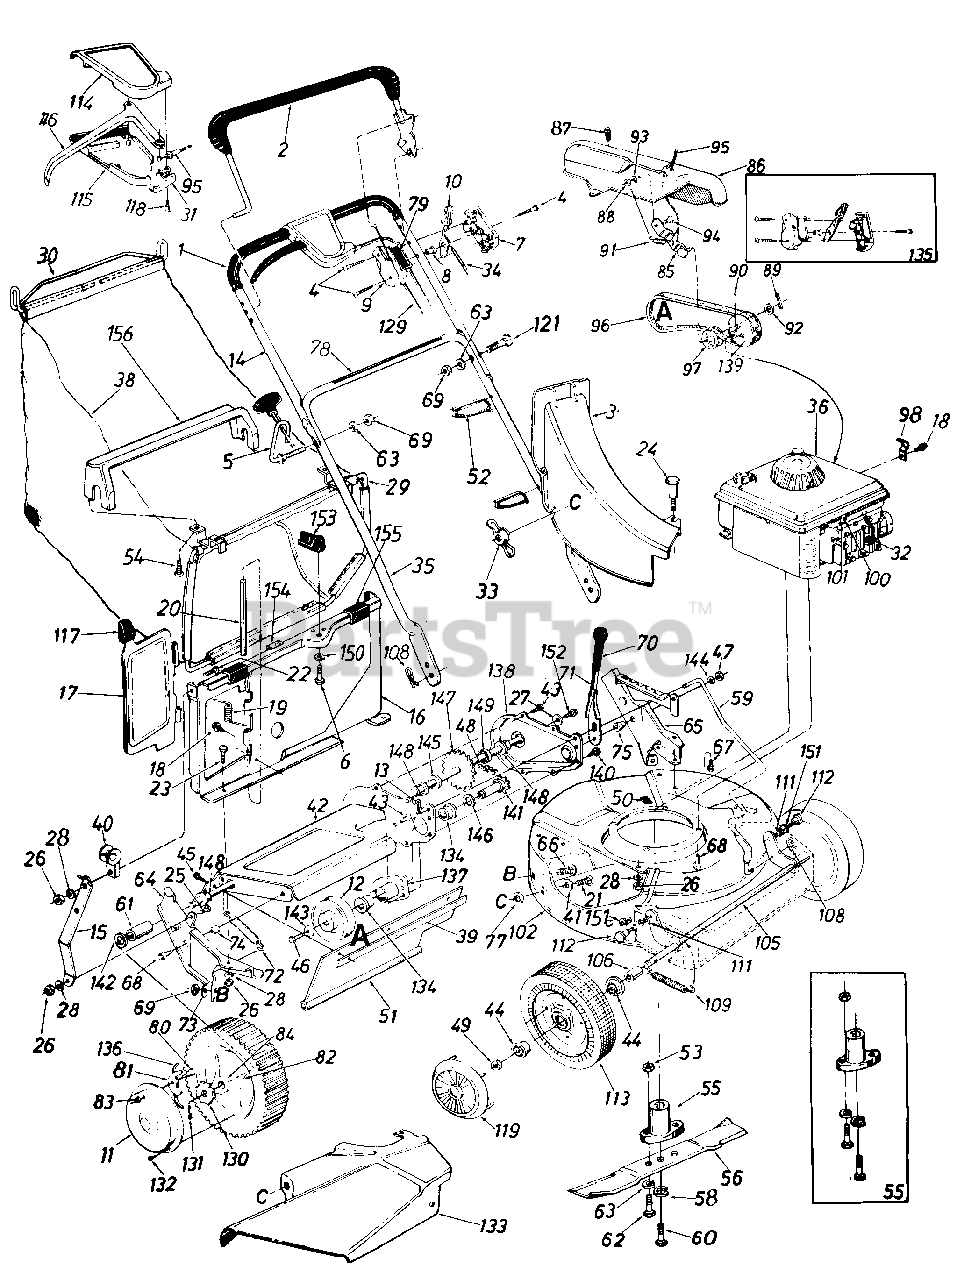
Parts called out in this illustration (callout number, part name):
2	Control Handle Assembly
3	Top Discharge Chute Assembly
4	Truss Machine Screw #12 x 1.5 "
5	Rope Guide Bolt
6	Hex Tap Screw 1/4-20 x 75 "
7	Control Panel Half
8	Control Disc Pin
9	Clutch Panel Half
10	Throttle Control Lever
11	Hub Cap
12	1/2" V Pulley
13	Cotter Pin 3/32" Diameter x 75"*
14	Upper Handle
15	Panel Support Bracket
16	Top Catcher Panel Assembly
17	Top Door
18	Hex B-Tap Screw #10 x .38 "
19	Torsion Spring
20	Pivot Pin
21	Carriage Bolt 1/4-20 x .62 "*
22	Truss Machine Screw 1/4-20 x 3/4 "
23	Hex Bolt 1/4-20 x .50"*
24	Shoulder Bolt
25	Hex Bolt 1/4-20 x 62"*
26	Hex Nut 1/4-20 Thread'
27	Belleville Washer 114" I . D .
28	Lock Washer 1/4" I.D.*
29	Front Grass Catcher Frame
30	Grass Catcher Handle
31	Control Cover
32	Spark Plug Insulator
33	Wing Nut
34	Throttle Control Wire 58 "
35	Lower Handle
36	Engine
38	21 " Top Discharge Grass Bag
39	Retaining Strip
40	Rope Guide
41	Flat Washer .344" I.D. x .62 "
42	Chain Axle Assembly
43	Hex B-Tap Screw 1/4" x .38 "
44	Flange Ball Bearing
45	Hex AB-Tap Screw 1/4 x .62 "
46	Hex TT-Tap Screw 1/4-20
47	Hex Patch Lock Nut 3/8-24 Thread
48	#48 Chain 5" Pitch x 30 Links
49	Hex Lock Nut 1/2-20 Thread
51	Rear Flap
52	Cable Tie
53	Hex Nut 5/16-24 Thread *
54	Hex AB-Tap Screw
55	Blade Adapter Kit
56	21" Blade
58	Lock Washer 3/8" I D.
59	Height Adjustment Rod
60	Hex Bolt 3/8-24 x 2 25" (Grade 5)
61	Spacer 51" I D.
62	Hex Bolt 5/16-24 x 1 0" (Grade 5)
63	Lock Washer 5/16" I D *
64	R.H. Handle Wheel Bracket Assembly
65	L.H. Handle Wheel Bracket Assembly
66	Carriage Bolt 5/16-18 x 62 "*
67	Hex B-Tap Screw 5/16-18
68	Hex TT-Tap Screw 3/8-16
69	Hex Nut 5/16-18 Thread *
71	Height Adjustment Lever
72	Extension Spring
73	Belleville Washer 5/16" I D.
74	Spacer 385" I.D.
75	Shoulder Spacer
77	Bolt Retainer
78	Instruction Label
79	Control Label
80	Shoulder Bolt
81	Pawl
82	Rear Wheel Assembly Complete
83	Hex Lock Nut 1/4-20 Thread
84	Flange Ball Bearing
85	Belt Idler Bracket Assembly
86	Belt Cover
87	Hex Self-Tap Screw 1/4-20 x 50 "
88	Hex Nut 1/4-20 Thread*
89	Cotter Pin 1/8" Diameter x 1.0"*
90	Spring Pin Spiral 3/16" Diameter
91	Extension Spring .33" O.D.
92	Flat Washer .531 " I.D.
93	Lock Washer 1/4" I.D.*
94	Shoulder Bolt
95	Cable-53" Long
96	"V"-Belt 1/2" x 32" Long
97	Flat Idler Pulley
98	Casing Clamp
100	Hex B-Tap Screw #10 x 62 "
101	Casing Clamp
106	Sleeve 526" I.D.
108	Internal Cotter Pin 5/16" Dia roeter
109	Extension Spring
111	Internal Lock Washer 3/8 I . D .
112	Shoulder Bolt
113	Front Wheel Assembly Complete
114	Self-Propelled Control Cover
115	Self-Propelled Control Cover
116	Control Lever
117	Door Grip
118	Counter Sunk Tap Screw #10 x .75"
119	Hub Cap-Plastic
121	Carriage Bolt 5/16-18 x 1 .38 "
129	Control Cable-43"
130	Ratchet Wheel
131	Cotter Pin 1/8" Diameter x l.O"
132	Pan Head Tap Screw #12 x .50"
133	Side Chute Deflector Assembly
134	Flange Bushing
135	Kit-Control Housing Complete
136	Spring-Nylon
137	Bearing Hub Flange Assembly
138	Chain Cover
139	Engine Pulley 1/2"
140	Hex Self-Tap Screw 1/4-20 x .50"
141	Sprocket Shaft Assembly
142	Flat Washer .531 " I.D. x .93" O.D.
143	Belleville Washer .265" I.D. x .75" O.D.
144	Flat Washer .385" I.D. x .87" O.D.
145	Flat Washer .51 " I.D. x 1.0" O.D.
146	Flat Washer .62" I.D. x 1.12" O.D.
147	Rear Shaft Assembly
148	Hex Flange Bearing
149	Spacer .510" I.D.
150	Spring Washer .32" I.D.
151	Flanged Nyliner Bearing
152	Hex Bolt 1/4-20 x .62" (Grade 5)
153	Grass Catcher Locking Knob
154	Foam Strip
155	Panel Clip
156	Bag Handle
